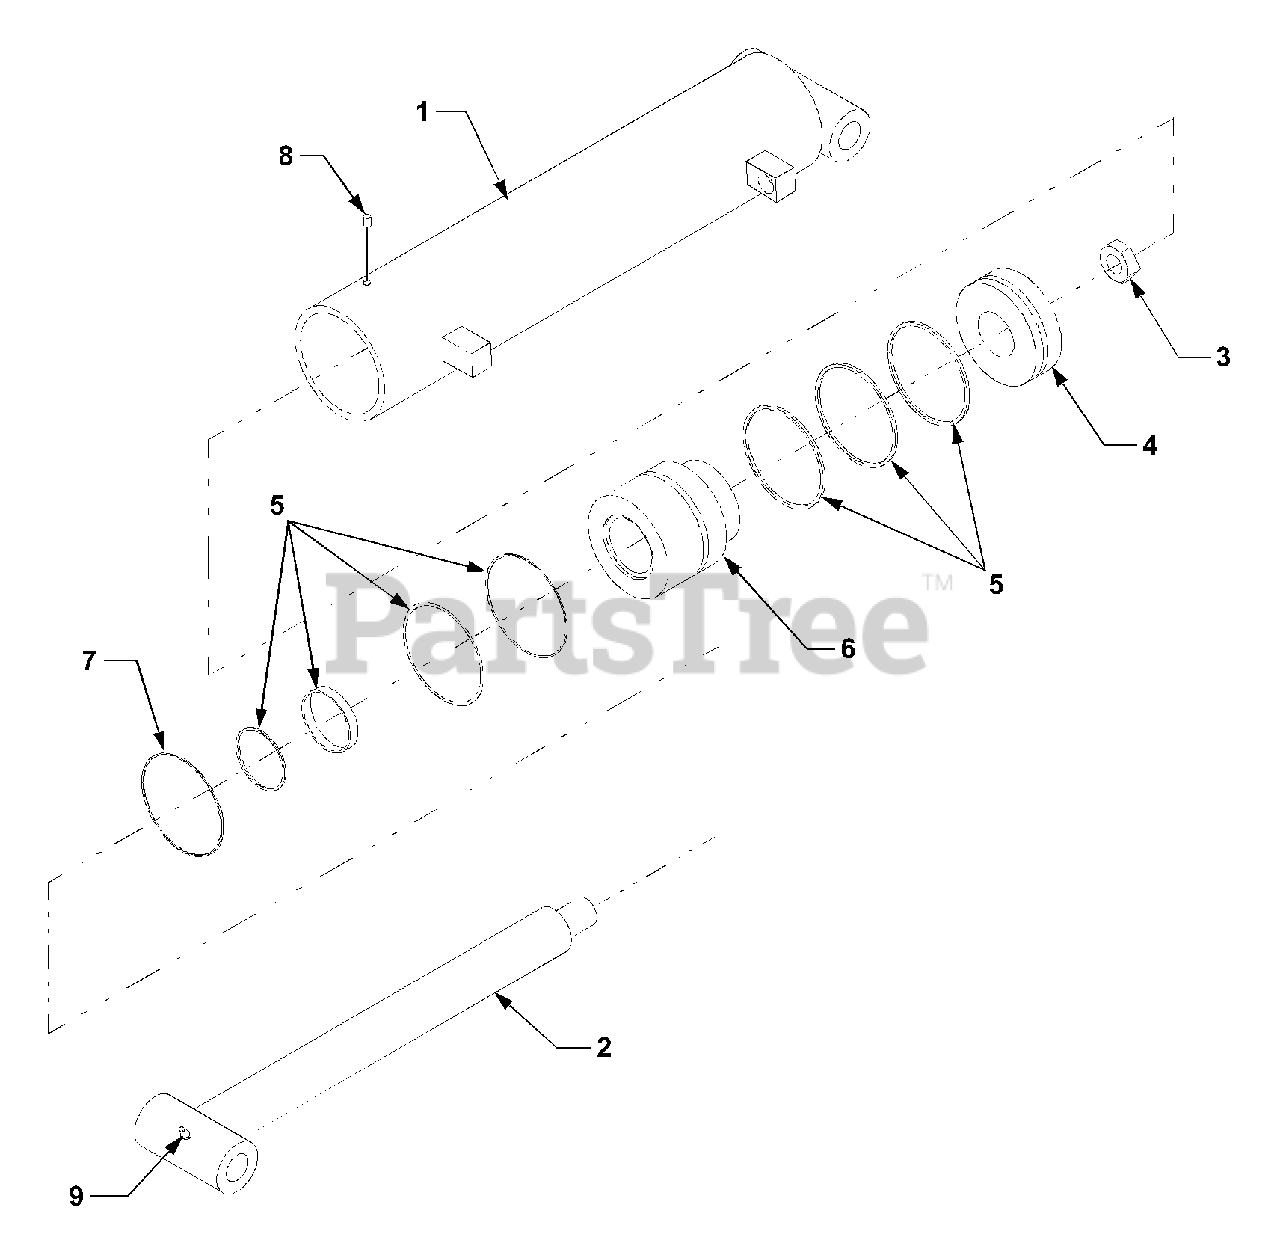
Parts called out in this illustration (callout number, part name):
1	Tube, LH Cylinder Assembly
2	Rod, LH Cylinder Assembly
7	Retaining Ring
9	Grease Fitting
